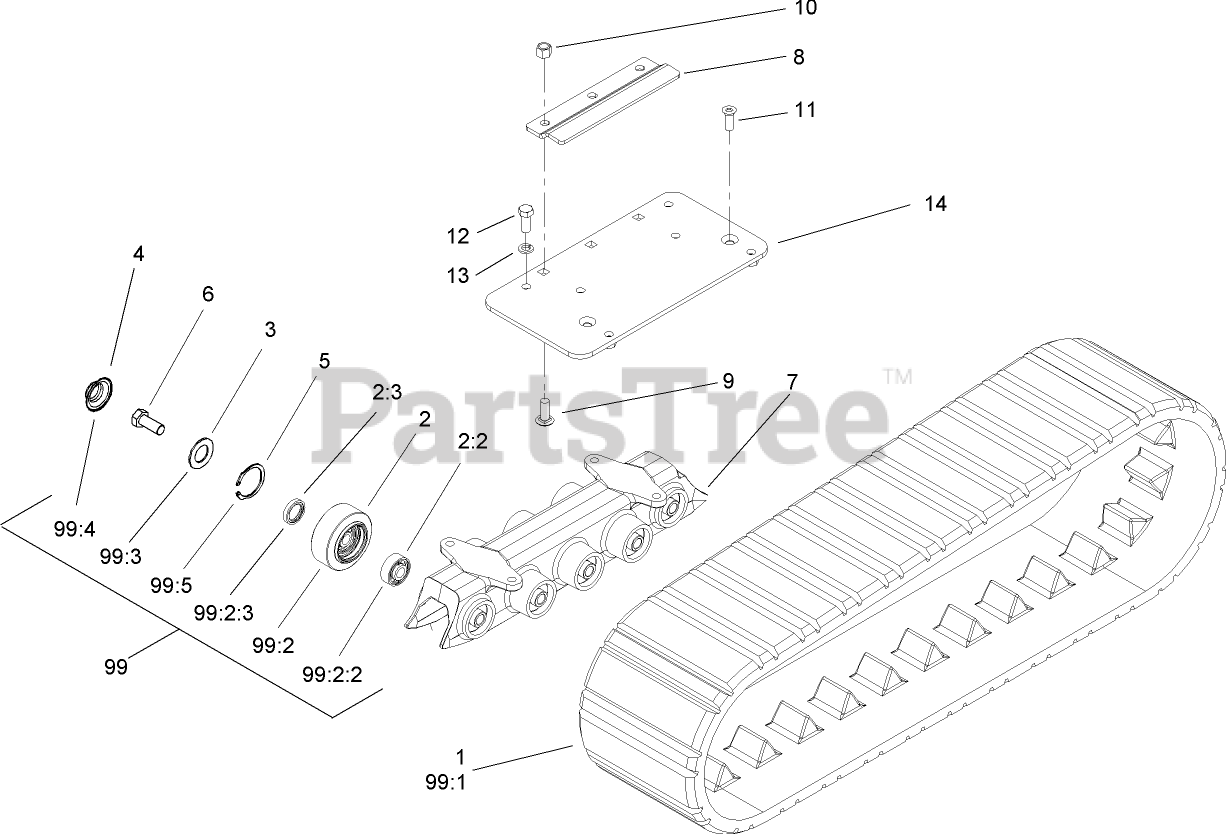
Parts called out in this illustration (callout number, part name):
1	TRACK
2	Road Wheel ASM
2:2	BEARING
2:3	SEAL-OIL
3	Gasket-Bogie
4	CAP-WHEEL, BEARING
5	RING-SNAP, INTERNAL
6	SCREW-HH
7	GUIDE-TRACK,REFIT
8	PLATE-CLAMP
9	SCREW-CARR, SHORT NECK
10	NUT-LOCK, NI
11	SCREW-HSFH
12	SCREW-HH
13	WASHER-LOCK
14	RH GUIDE ADAPTER PLATE ASM
99	TRACK REBUILD KIT
99:1	TRACK
99:2	Road Wheel ASM
99:2:2	BEARING
99:2:3	SEAL-OIL
99:3	Gasket-Bogie
99:4	CAP-WHEEL, BEARING
99:5	RING-SNAP, INTERNAL
